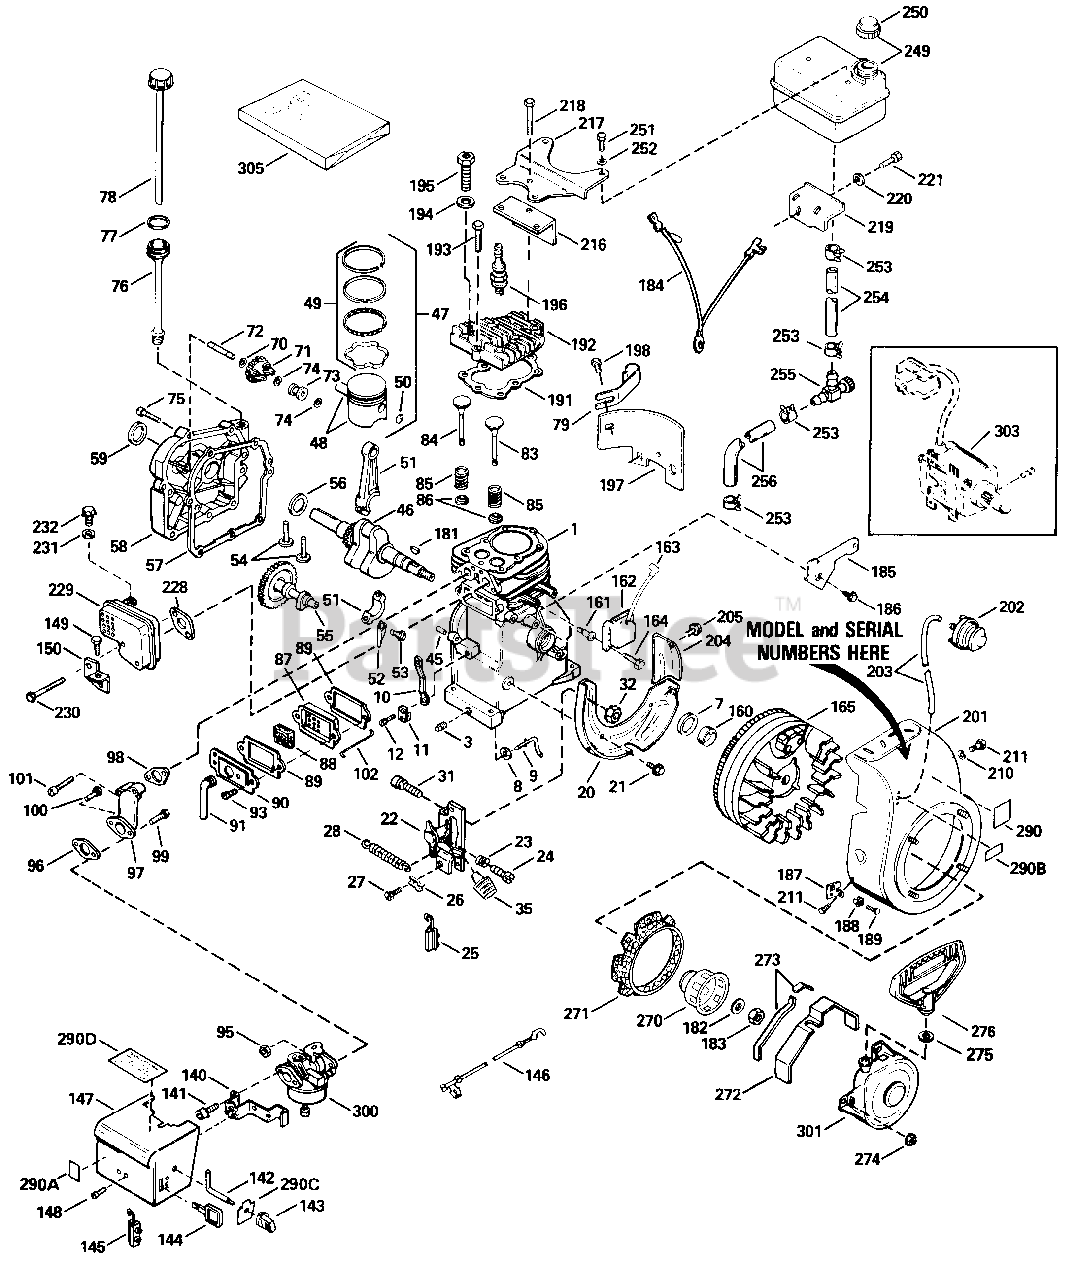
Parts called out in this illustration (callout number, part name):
1	Cylinder Ass'y.
3	Plug, Pipe, 1/4-18
7	Seal, Oil
8	Washer, Flat
9	Rod, Governor
10	Lever, Governor
11	Clamp, Governor Lever
12	Screw, Hex Washer Hd., 8-32 x 5/16
20	Baffle, Blower Housing
21	Screw, Hex Washer Hd. Durlok, 1/4-20 x 5/8
22	Control Ass'y., Bracket
23	Spring Compression
24	Screw, Fil. Hd., 5-40 x 7/16
25	Terminal Ass'y.
26	Clip, Conduit
27	Screw, Hex Washer Hd. Sems, 10-32 x 3/8
28	Spring, Extension
31	Screw, Fil. Hd. Sems, 8-32 x 1/2
32	Nut, Lock, 8-32
35	Knob, Speed Control
45	Pin, Dowel
46	Crankshaft Ass'y.
47	Piston, Pin & Ring Ass'y. (Std.)
48	Piston & Pin Ass'y. (Std.)
49	Ring Set, Piston (Std.)
50	Ring Piston Pin Retaining
51	Rod Ass'y., Connecting
52	Dipper, Oil
53	Bolt, Connecting Rod
54	Lifter, Valve
55	Camshaft (Compression Release)
56	Washer, Thrust
57	Gasket, Cylinder Cover
58	Cover, Cylinder
59	Seal, Oil
70	Washer, Flat
71	Gear, Governor
72	Shaft, Mechanical Governor
73	Spool, Governor
74	Ring, Retaining
75	Screw, Hex Hd. Sems, 1/4-20 x 1-1/4
76	Tube Ass'y., Oil Fill
79	Clip, Oil Fill
83	Valve Exhaust
84	Valve Intake
85	Spring, Valve
86	Cap, Valve Spring
87	Body, Valve Cover
88	Element, Valve Body
89	Gasket, Valve Cover
90	Cover, Breather
91	Tube Breather
93	Screw, Fil. Hd. Sems, 10-24 x 1/2
95	Nut & Lock Washer Ass'y. 1/4-28
96	Gasket, Carburetor
97	Pipe, Intake
98	Gasket, Intake
99	Screw, Hex Hd., 1/4-28 x 7/8
100	Screw, Hex Hd., 1/4-28 x 1-11/16
101	Screw, Fil. Hd. Sems, 1/4-20 x 1-11 9/32
102	Link, Governor to Throttle
140	Bracket, Choke
141	Screw, Fil. Hd. Sems, 10-32 x 1/2
142	Rod, Choke
143	Knob, Choke Control
144	Key, Ignition
145	Terminal Ass'y.
146	Wire, Ground
147	Cover, Carburetor
148	Screw, Pan Hd. Sems, 8-32 x 5/16
149	Screw, Hex Hd. Sems, Taptite, 10-24 x 3/8
150	Bracket, Carburetor Cover
160	Spacer, Flywheel Key
161	Stud, Solid State Mounting
162	Solid State Ass'y.
163	Cover, Spark Plug
164	Screw, Hex Hd. Sems, 10-24 x 1
165	Flywheel (w/Ring Gear)
181	Key Flywheel
182	Washer, Belleville
183	Nut Flywheel
184	Wire, Ground
185	Bracket, Hld Down
186	Screw, Hex Washer Hd. Self-Tap Sems, 10-24 x 9/16
187	Bracket, Grommet Mounting
188	Grommet, Plastic
189	Screw, Pan Hd. Taptite, 8-32 x 3/8
191	Gasket, Cylinder Cover
192	Head, Cylinder
193	Screw, Hex Flanged Hd., 5/16-18 x 1 1/2
194	Washer, Flat
195	Screw, Special Hex Hd., 5/16-18 x 1 1/2
196	Plug, Spark
197	Extension, Blower Housing
198	Screw, Fil. Hd. Sems, 10-24 x 1/2
201	Housing, Blower
202	Primer Ass'y.
203	Line Primer
204	Extension, Baffle
205	Screw, Hex Washer Hd. Shake- proof Self-Drilling, 8-18 x 7/16
210	Washer, Flat
211	Screw, Hex Hd. Sems, 1/4-28 x 7/16
216	Baffle, Heat
217	Plate, Fuel Tank
218	Screw, Hex Flange Hd., 5/16-18 x 2
219	Bracket, Fuel Tank Mounting
220	Washer, Flat
221	Screw, Hex Hd. w/Belleville Washer, 1/4-20 x 11/16
228	Gasket, Exhaust
229	Muffler
230	Screw, Fil. Hd. Sems, 1/4-20 x 2 1/2
231	Washer, Flat
232	Screw, Hex Washer Hd. Sems, 1/4-20 x 1/2
249	Tank Ass'y., Fuel
250	Cap, Fuel Tank
251	Screw, Hex Washer Hd. Self-Tap Sems, 1/4-15 x 7/8
252	Washer, Flat
253	Clamp, Fuel Line
254	Line, Fuel
255	Valve, Shut-Off
256	Line, Fuel
270	Cup, Starter
271	Screen, Starter Cup
272	Guard, Starter
273	Seal, Snow Guard
274	Nut & Lock Washer, 1/4-28
275	Washer, Flat
276	Handle, Starter
290	Decal, Name
290A	Decal, Instruction
290B	Decal, Primer
290C	Decal, Choke
290D	Decal, Warning
300	Carburetor
301	Starter, Rewind
303	Electric Starter Kit
305	Gasket Set
